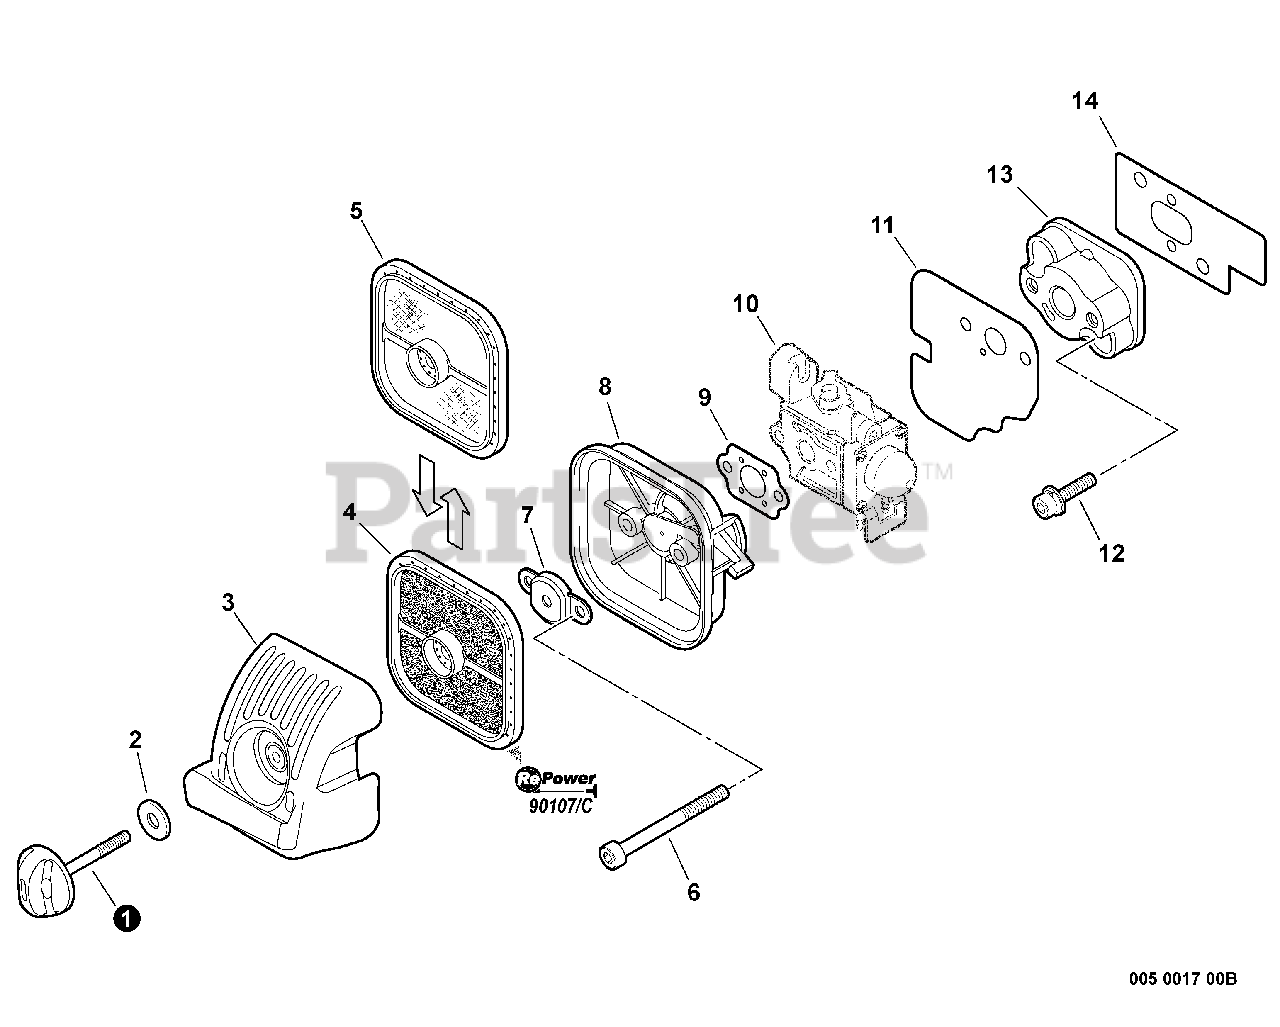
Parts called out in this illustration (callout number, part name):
1	THUMBSCREW
3	COVER, AIR FILTER
4	FILTER, AIR - DOUBLE LAYER
5	FILTER, AIR - SINGLE LAYER
6	SCREW - 5X60
7	PLATE, PREVENT
8	AIR FILTER CASE ASSY
9	GASKET, INTAKE
10	CARBURETOR
11	GASKET, INTAKE
12	SCREW - 5X25
13	INSULATOR, INTAKE
14	GASKET, INTAKE
16	RePower TUNE-UP KIT
